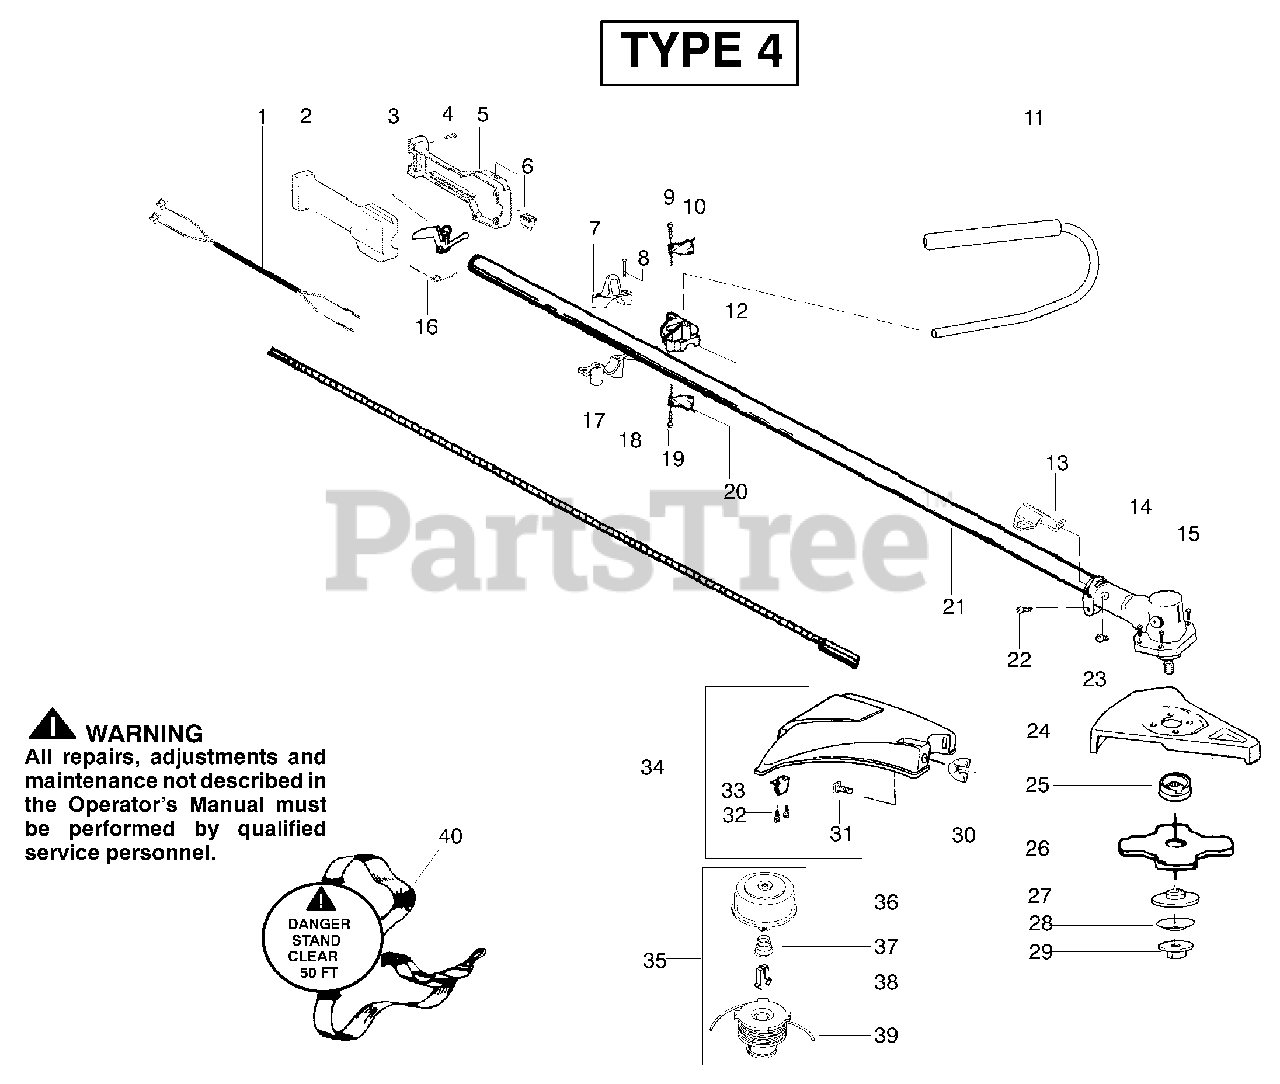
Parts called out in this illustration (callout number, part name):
1	Assy--Leadwire
2	Hsg.--Throttle Right
3	Lever--Throttle
5	Hsg.--Throttle Left
6	Kit--On/Off Switch
7	Clamp--Upper
10	Bracket--Handlebar
11	Kit--Handlebar Assy. w/decal
12	Clamp--Handlebar
13	Bracket--Shield
14	Kit--Gear Box Ass'y.
16	Spring--lever return
17	Clamp--Lower
18	Shaft--Flex
20	Bracket--Handlebar
21	Kit--Drive Shaft Assy
24	Kit--Metal Shield
25	Dust Cup
26	Accy--4 Point Blade
28	Washer--Belleville
29	Nut--Flange
30	Wingnut
32	Screw
33	Line Limiter
34	Kit--Shield Ass'y.
35	Accy--Cutting Head
36	Assy--Hub
37	Spring--Return
38	Retainer--Spool
39	Accy--Spool w/Line
40	Assy--Shoulder Strap
